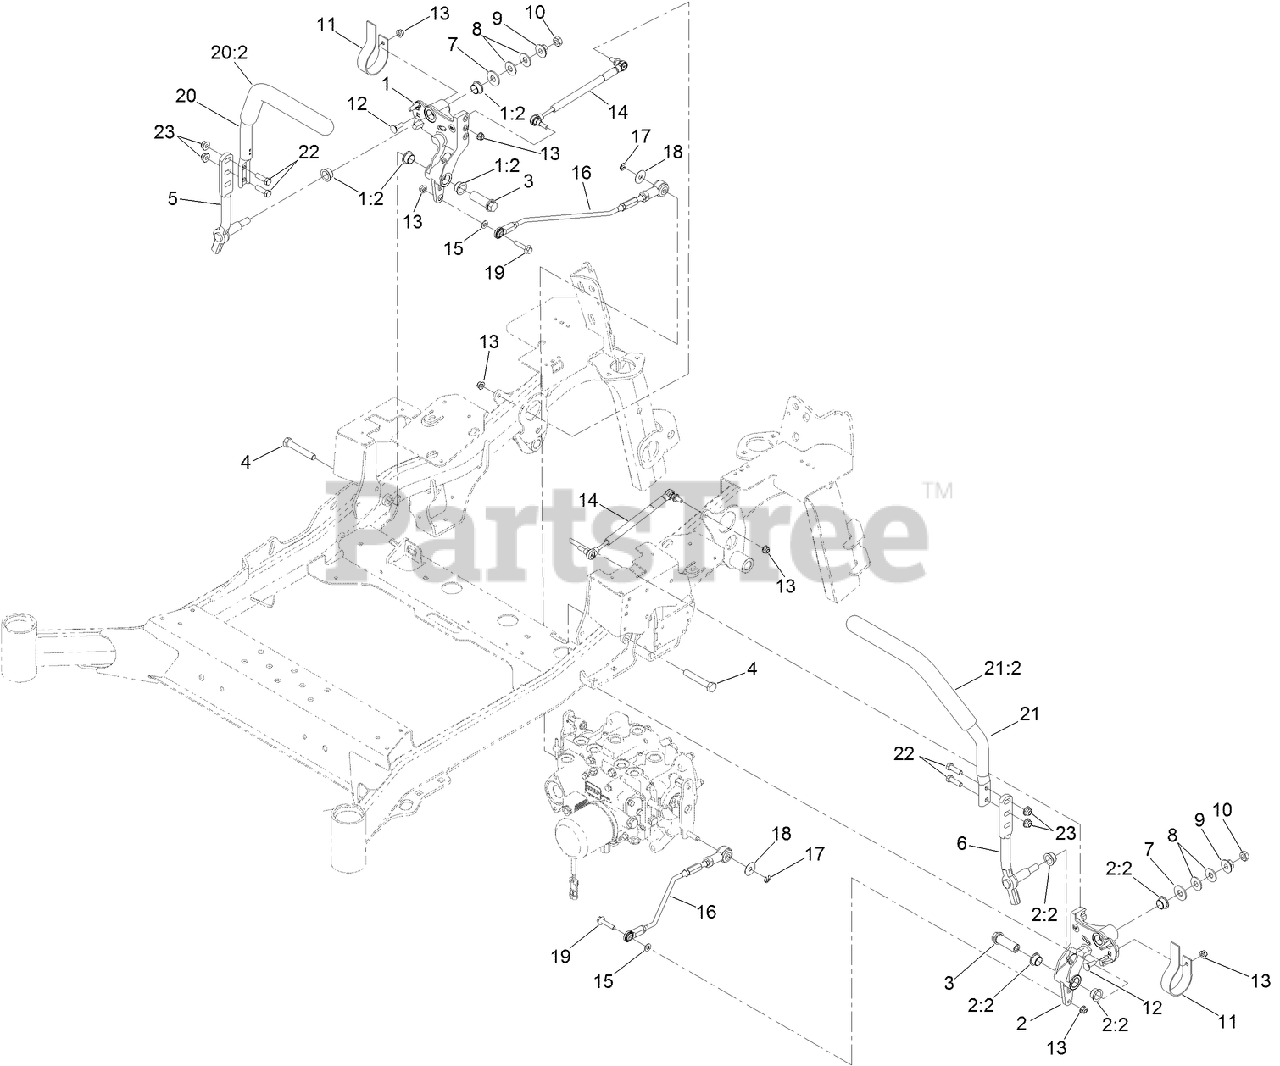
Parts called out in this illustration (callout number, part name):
1	RH MOTION CONTROL AND BUSHING ASM
1:2	BUSHING-FLANGE
2	LH MOTION CONTROL AND BUSHING ASM
2:2	BUSHING-FLANGE
3	HUB-THREADED
4	SCREW-HH
5	LEVER-CONTROL MOTION, RH
6	LEVER-CONTROL MOTION, LH
7	WASHER-FLAT
8	WASHER-SPRING
9	NUT-HF
10	NUT-JAM
11	SPRING-LEAF
12	BOLT-CARR
13	NUT-HF, NI
14	DAMPER-CONTROL, MOTION
15	WASHER-PLAIN
16	FRONT LINKAGE ROD ASM
17	RING-RETAINING
18	WASHER-PLAIN
19	SCREW-HHF
20	RH STEERING HANDLE ASM
20:2	GRIP-CONTROL, LEVER
21	LH STEERING HANDLE ASM
21:2	GRIP-CONTROL, LEVER
22	SCREW-HH
23	NUT-HF, NI
